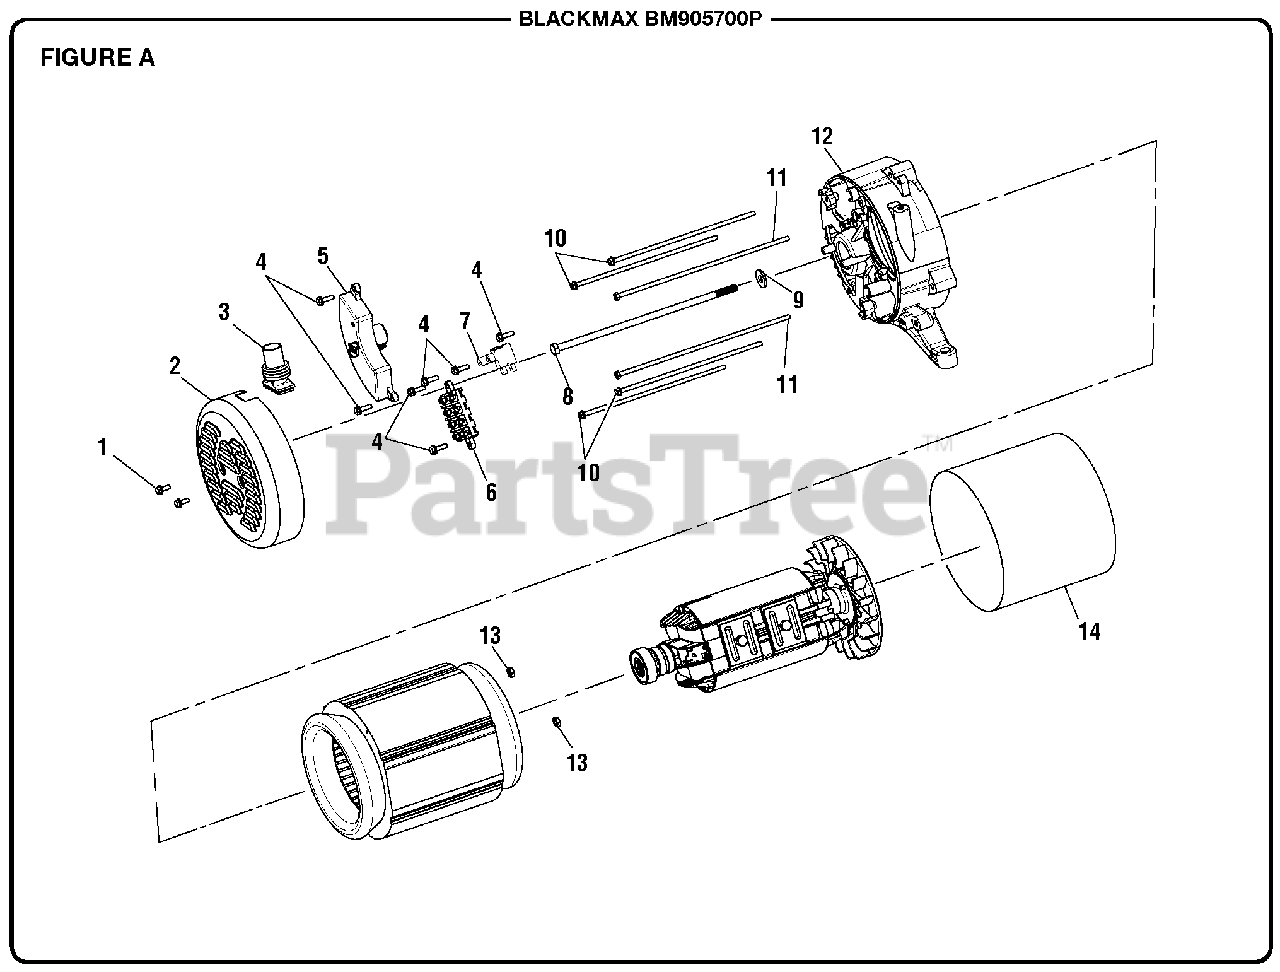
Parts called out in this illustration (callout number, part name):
1	Bolt (M5 x 10 mm, Hex Hd.)
2	Brush Cover
3	Rubber Boot
4	Bolt (M5 x 16 mm, Hex Hd.)
5	Automatic Voltage Regulator
6	Terminal Block
7	Brush Assembly Kit
8	Rotor Bolt (M12.7 x 242 mm, Hex Hd.)
9	Washer (5/16 in.)
10	Stator Bolt (1/4-20 x 7.5 in.)
11	Bolt (M5 x 230 mm, Hex Hd.)
12	Bearing Housing
13	Hex Nut (M5)
14	Generator Head Cover
